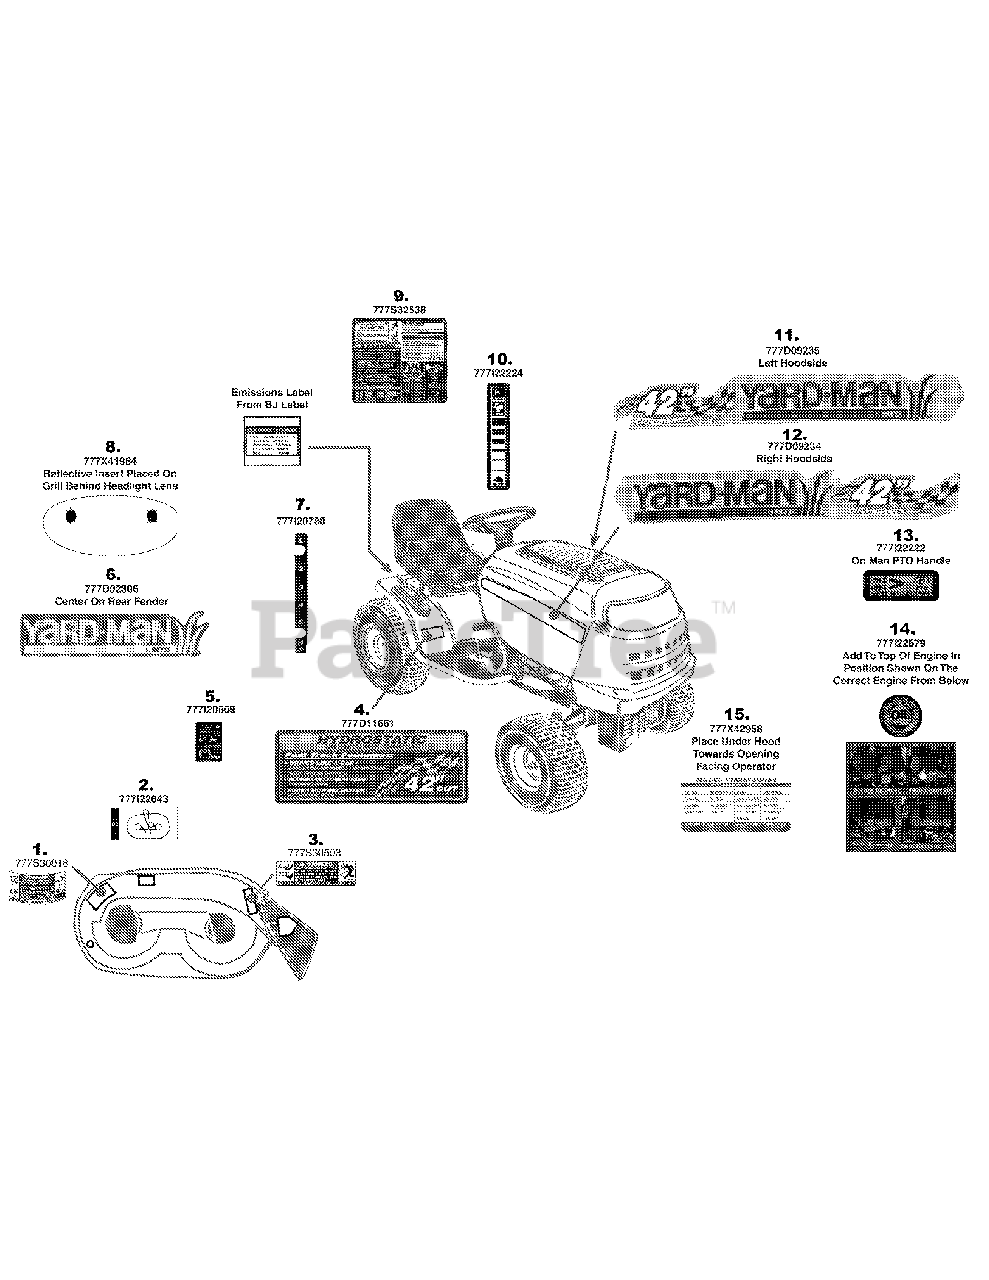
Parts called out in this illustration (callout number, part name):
1	LABEL-DECK SAFETY
2	LABEL-DECK BELT ROUTE 42"
3	LABEL-DANGER CHUTE
4	LABEL-RIDER YARDMAN UNDER SEAT 42"
5	LABEL-HITCHPLATE
6	LABEL-REAR FENDER
7	LABEL-SIDE FENDER
8	LABEL:RIDER 1&5 STYLE GRILL
9	LABEL:RIDER:SAFETY AUTO W/CRUISE
10	LABEL-DASH RH
11	LABEL:RIDER HOOD
12	LABEL:RIDER HOOD
13	LABEL-PTO HANDLE
14	LABEL-CHECK ENG OIL
15	LABEL-RIDER UNDER HOOD X615G
